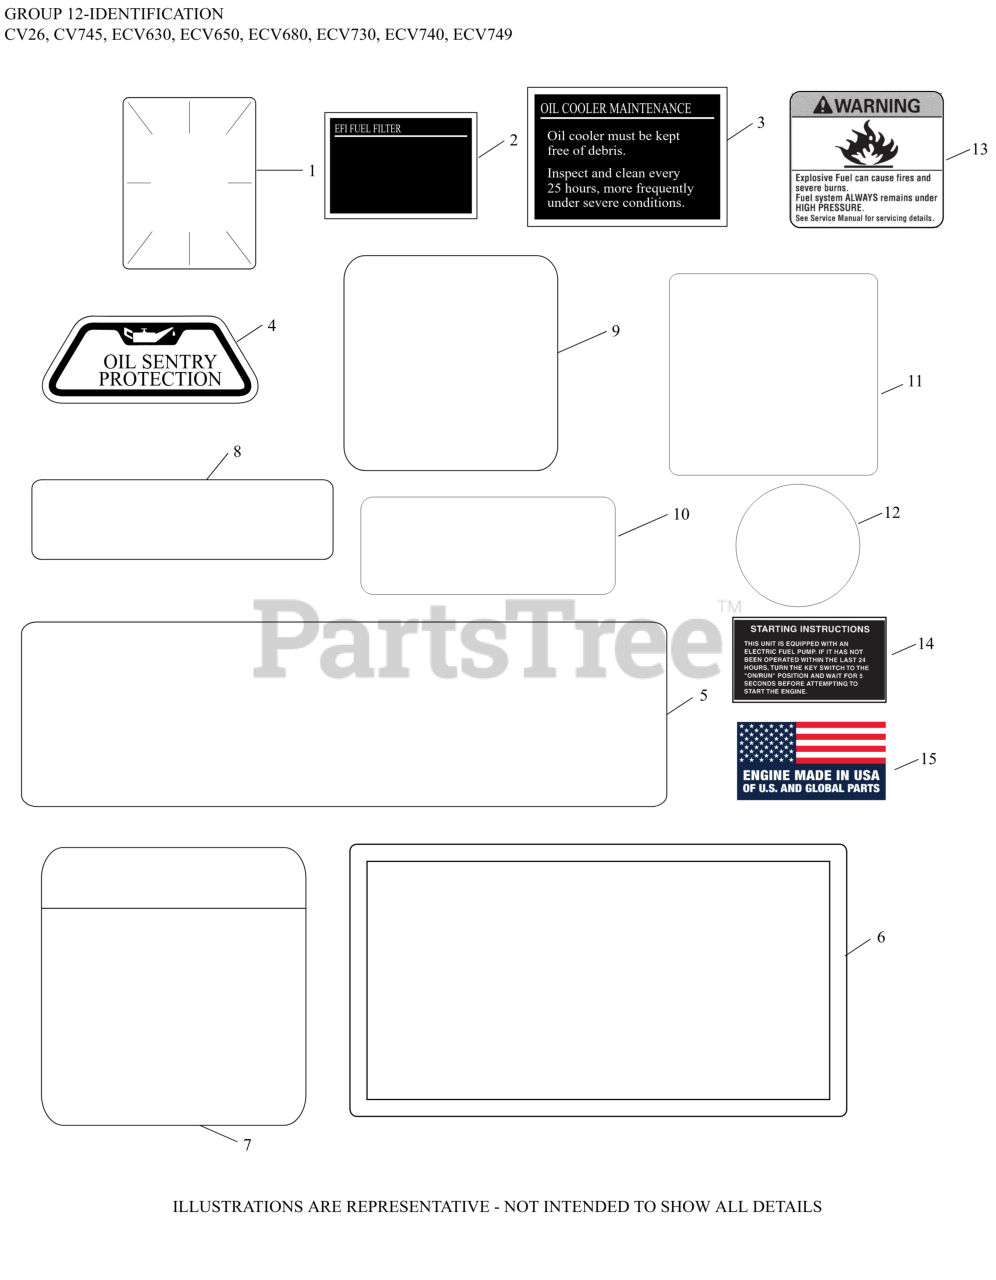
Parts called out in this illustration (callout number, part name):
1	LABEL, CLEAR LAMINATION
2	LABEL, EFI FUEL FILTER
8	DECAL LPAC, 26.5 HP/747cc/ECV-ECH749
